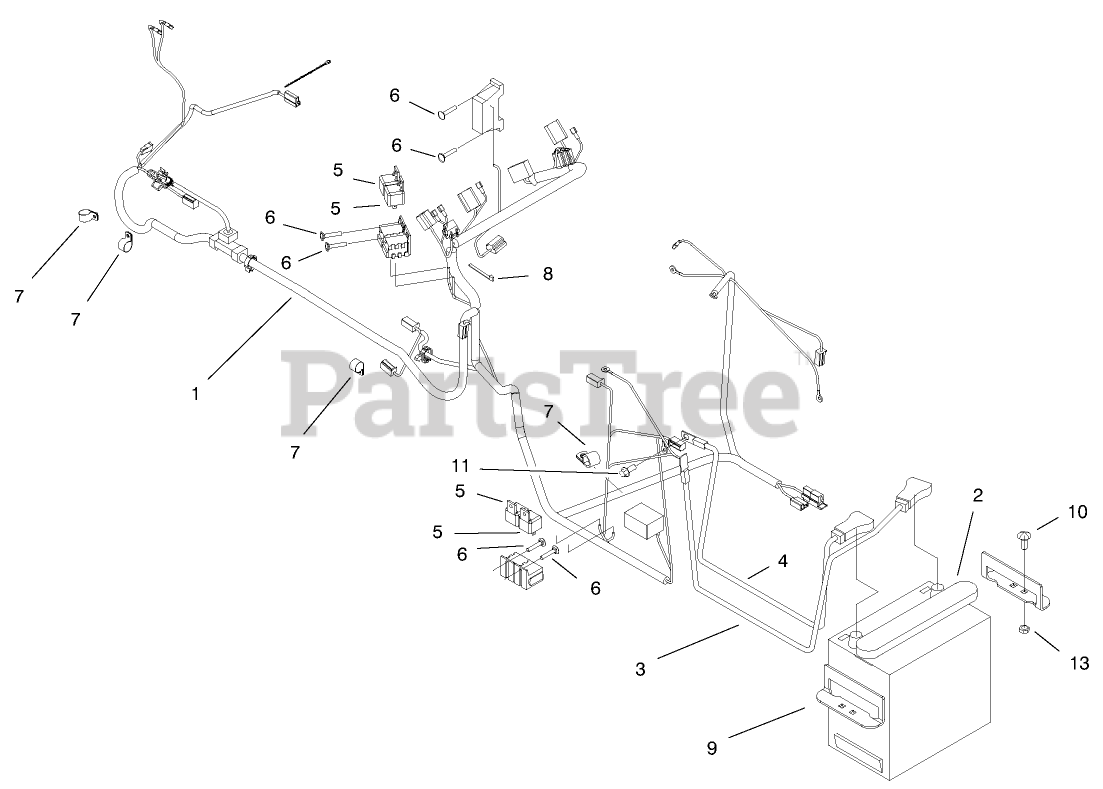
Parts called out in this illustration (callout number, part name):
1	HARNESS - MAIN DS
2	BATTERY, DRY - 495CCA
3	CABLE - BATTERY,RED
5	RELAY
6	SCREW
7	CLAMP - R
8	TIE-CABLE
9	HOLD - DOWN, BATTERY
10	BOLT-CARR
11	SCREW-HHF
13	NUT-LOCK, NI
